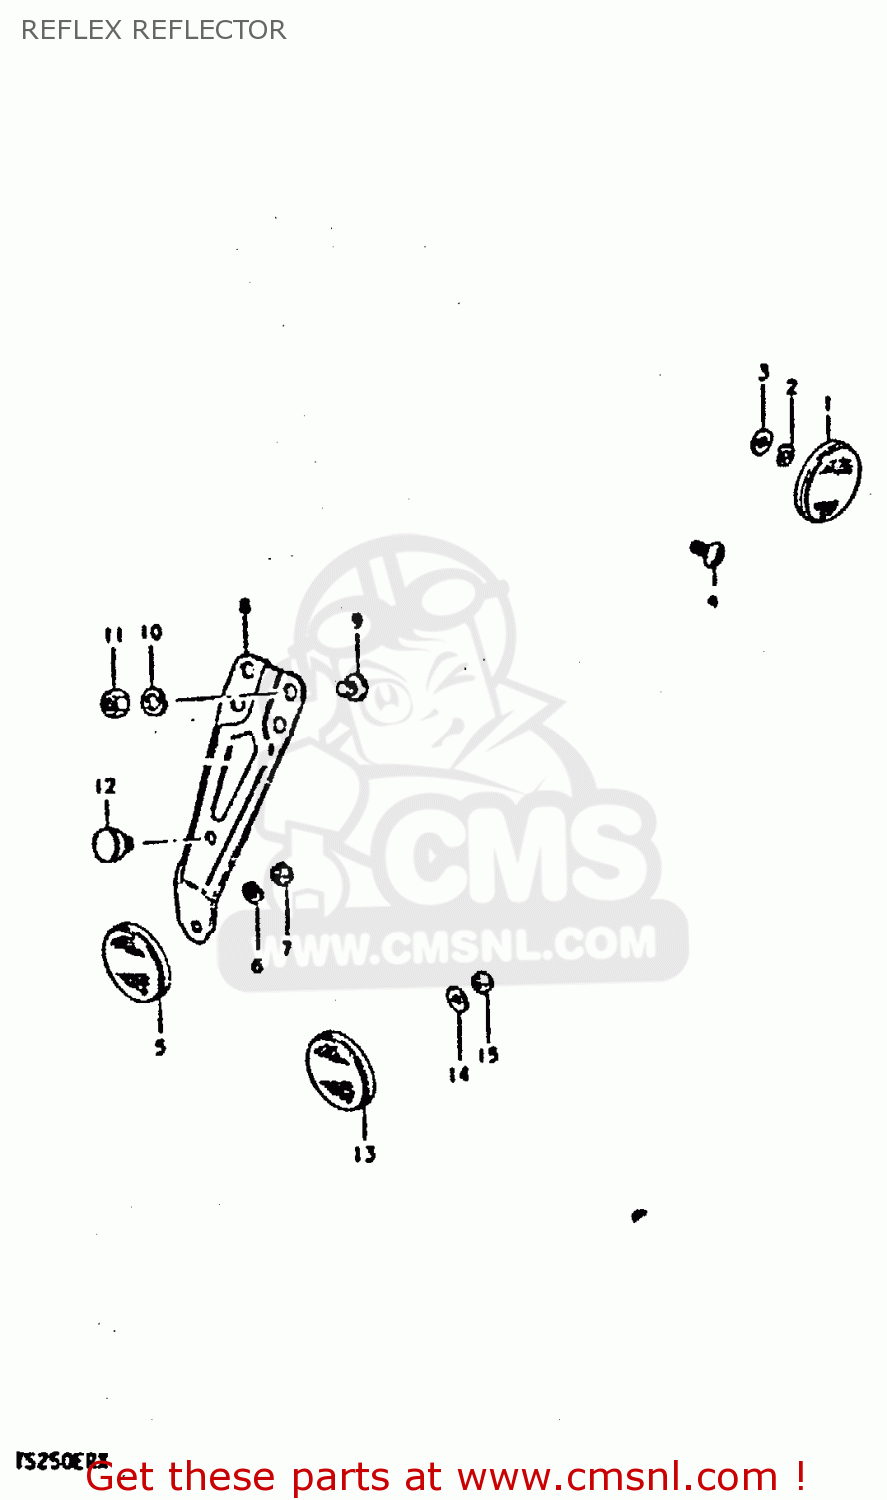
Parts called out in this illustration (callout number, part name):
1	REFLEX REFLECTOR,FR
2	LOCK WASHER
3	WASHER
5	REFLEX REFLECTOR,RR
6	WASHER
7	NUT
8	BRACKET
9	SCREW
10	LOCK WASHER
11	NUT
12	CUSHION
